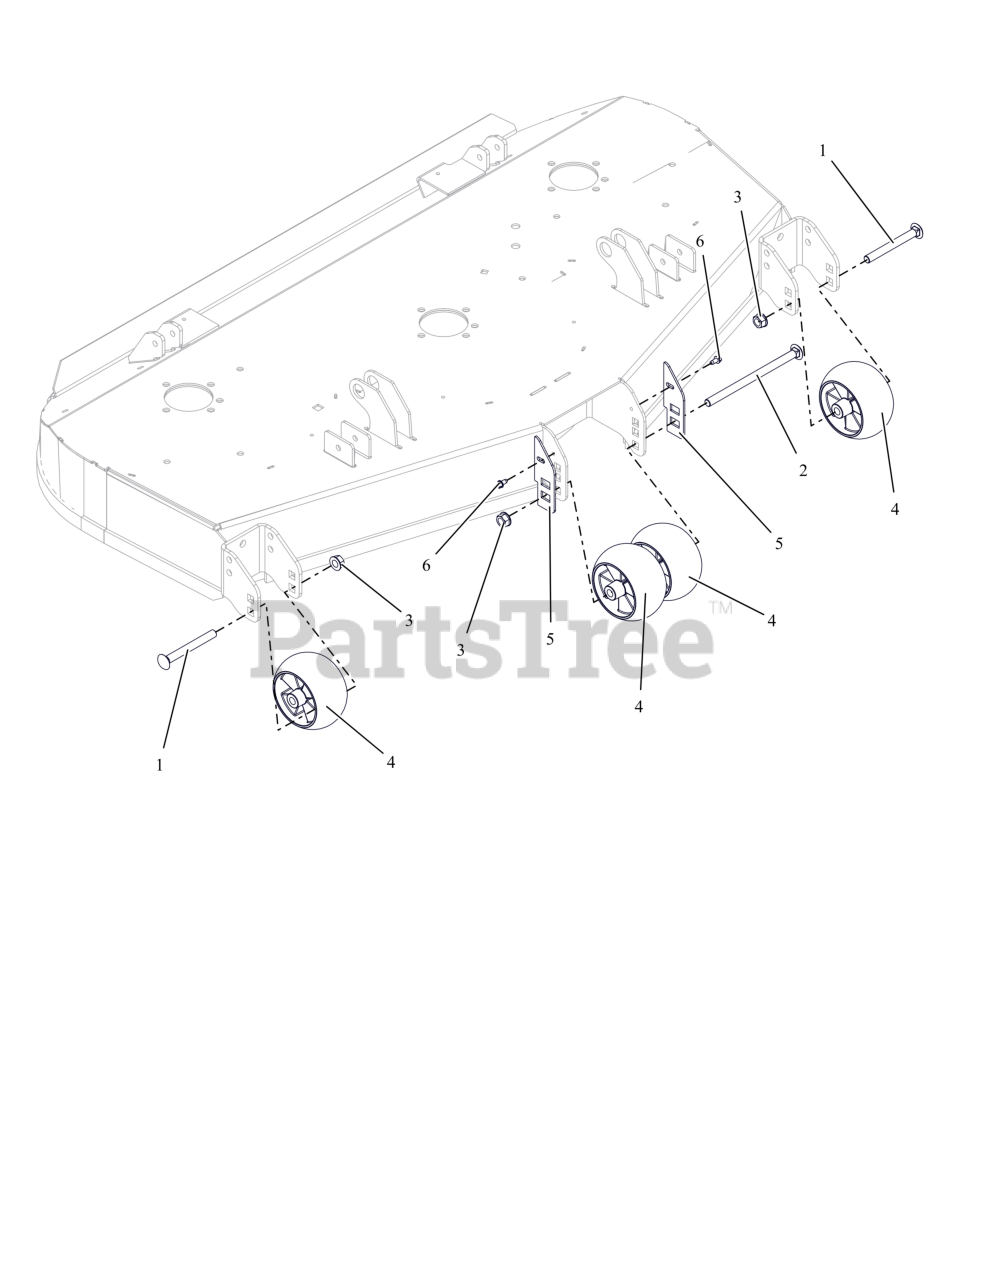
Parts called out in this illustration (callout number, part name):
1	BLT-RHNS .50-13X4.50 G5 ZCC NS
2	BLT-RHSN .50-13X8.00 G5 ZCC NS
3	NUT-LK-CTR-FLG .500-13 GG ZCC
4	WHEEL, ANTI SCALP - 5X3 CTR W/RIBS
5	PLATE, ANTI SCALP WHEEL 60" (ORANGE)
6	SCR-TAP .25-20X.50 HWH ZCC
